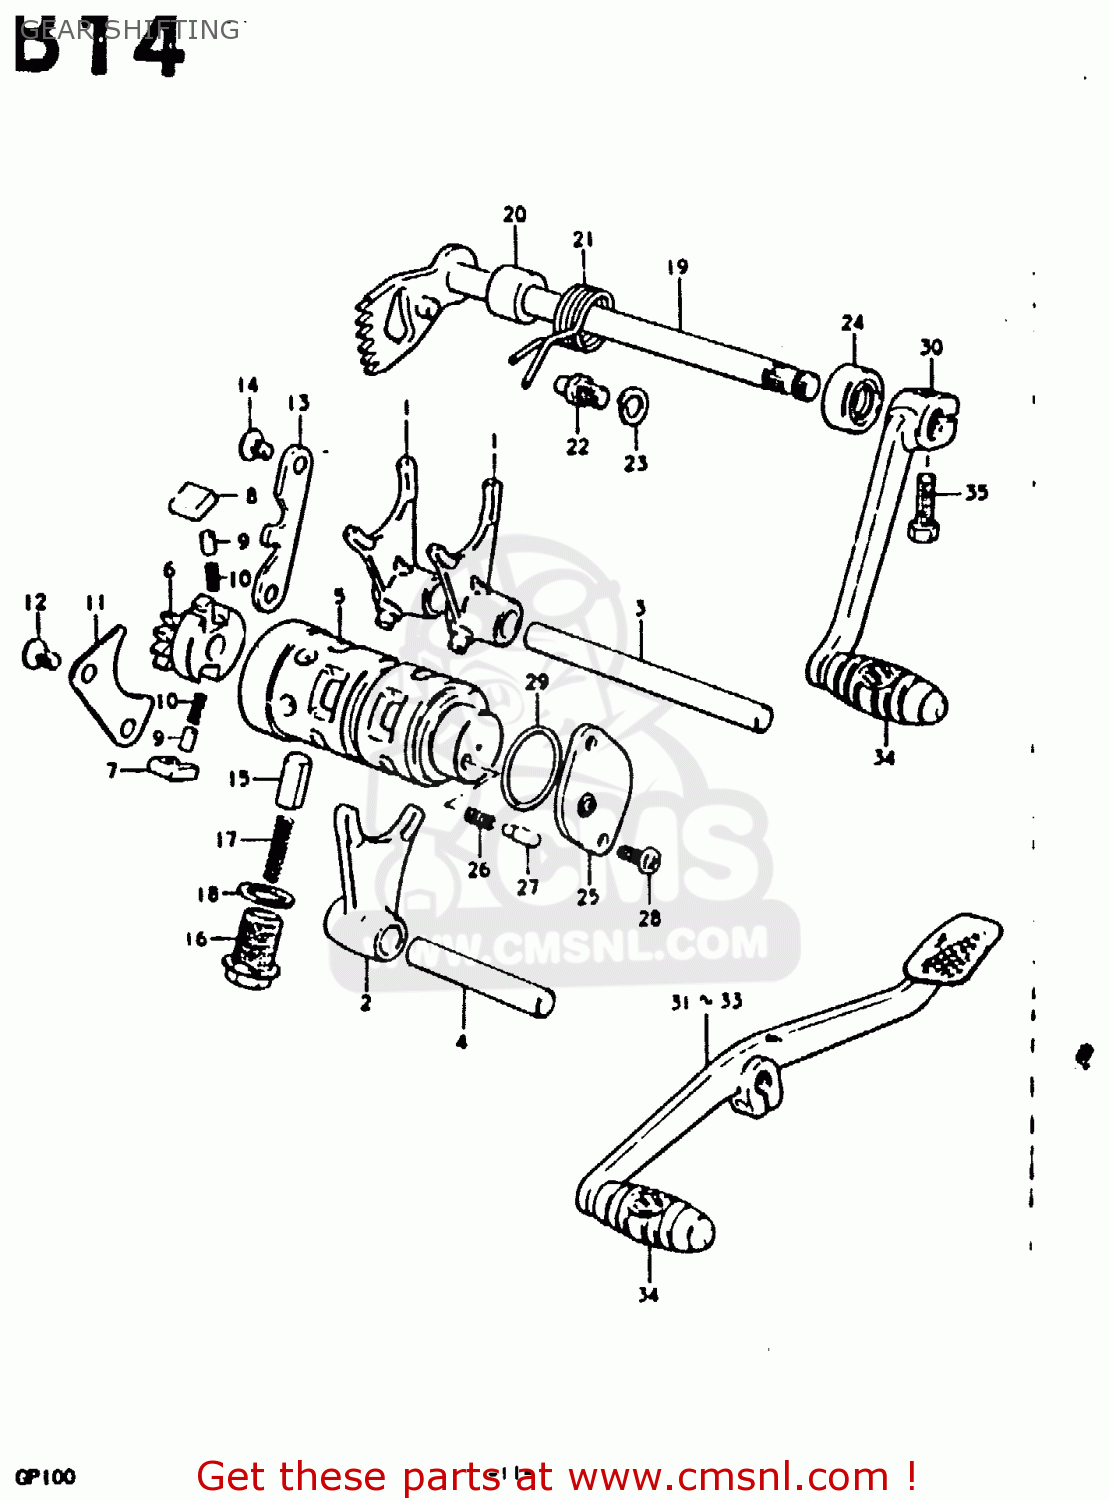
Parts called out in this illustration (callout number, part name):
1	FORK,GEAR SHIFT NO.1
2	FORK,GEAR SHIFT NO.2
3	SHAFT,GEAR SHIFT FORK
4	SHAFT,GEAR SHIFT FORK
5	CAM,GEAR SHIFT
6	RETAINER,GEAR SHIFT CAM
7	PAWL,GEAR SHIFT NO.1
8	PAWL,GEAR SHIFT NO.2
9	PIN(5X8)
10	SPRING
11	LIFTER,GEAR SHIFT PAWL
12	SCREW
13	GUIDE,GEAR SHIFT CAM
14	SCREW
15	STOPPER,GEAR SHIFTING
16	BOLT,GEAR SHAFT CAM STOPPER
17	SPRING
18	GASKET(14X19.2X2) (NAS)
19	SHAFT,GEAR SHIFT
20	SPACER(12X20X15.3)
21	SPRING
22	STOPPER,GEAR SHIFT CAM
23	WASHER
24	OIL SEAL
25	BODY,GEAR SHIFT SWITCH
26	SPRING
27	PIN(5X15.5)
28	SCREW
29	O-RING (D:2.4 ID:26.2)
30	LEVER ASSY,GEAR SHIFT
31	LEVER ASSY,GEAR SHIFT
33	LEVER ASSY,GEAR SHIFT
34	RUBBER,GEAR SHIFT PEDAL
35	BOLT
